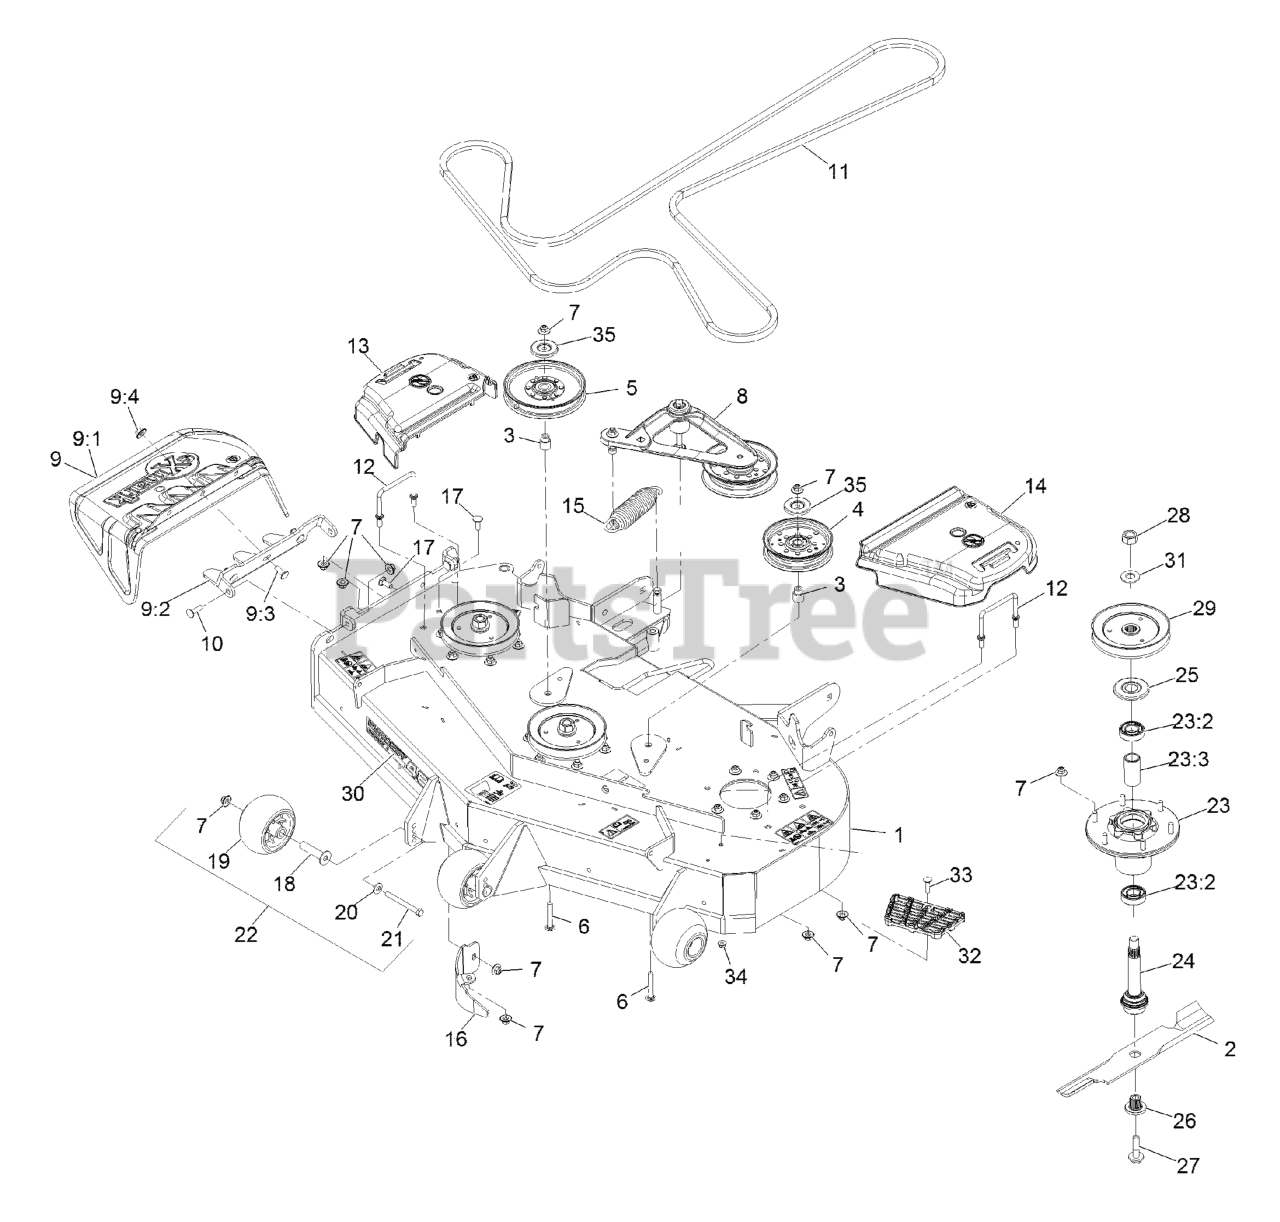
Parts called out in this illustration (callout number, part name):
1	DECK ASM,W/DECALS 60
2	Blade-Extreme 2, 20.50"
3	BUSHING-IDLER
4	IDLER-PULLEY
5	DECK IDLER ASM
6	PULLEY-IDLER, FLAT
8	SPRING-EXTENSION
9	SCREW-CARR
10	Nut-Nyloc 3/8-16 Flg
11	DOGLEG - LZ60
12	SCREW-CARR
13	WIREFORM-COVER
14	COVER-BELT, RH
15	COVER-BELT, LH
16	ASM,DISCHARGE CHUTE
16:1	CHUTE,DISCHARGE
16:2	BRACKET,DISCHARGE CHUTE
16:3	SCREW-CARR
16:4	Nut-Nyloc 3/8-16 Flg
17	Bolt-Carriage 3/8-16 X 1 1/4
18	AXLE, ROLLER
19	ROLLER-SCALP, ANTI
20	WASHER-BELLEVILLE
21	SCREW-HH 3/8-16 X 3 3/4 GR 8
22	KIT, ANTI-SCALP ROLLER
23	ASM-CUTTER HSG WITH BEARINGS
23:2	BEARING-BALL
23:3	SPACER-BEARING
24	ASM-SPINDLE AND SEAL
25	GUARD,BEARING TOP .989
26	BUSHING,SPLINED
27	SCREW,SEMS 1/2-20 X 2.19
28	NUT-HEX
29	SHEAVE,BLADE DRIVE 7.25
30	DECAL, 604
32	STEP-DECK
33	Bolt-Carriage 5/16-18 X 1 1/4
34	NUT-HF, NI
35	SHIELD-DUST
